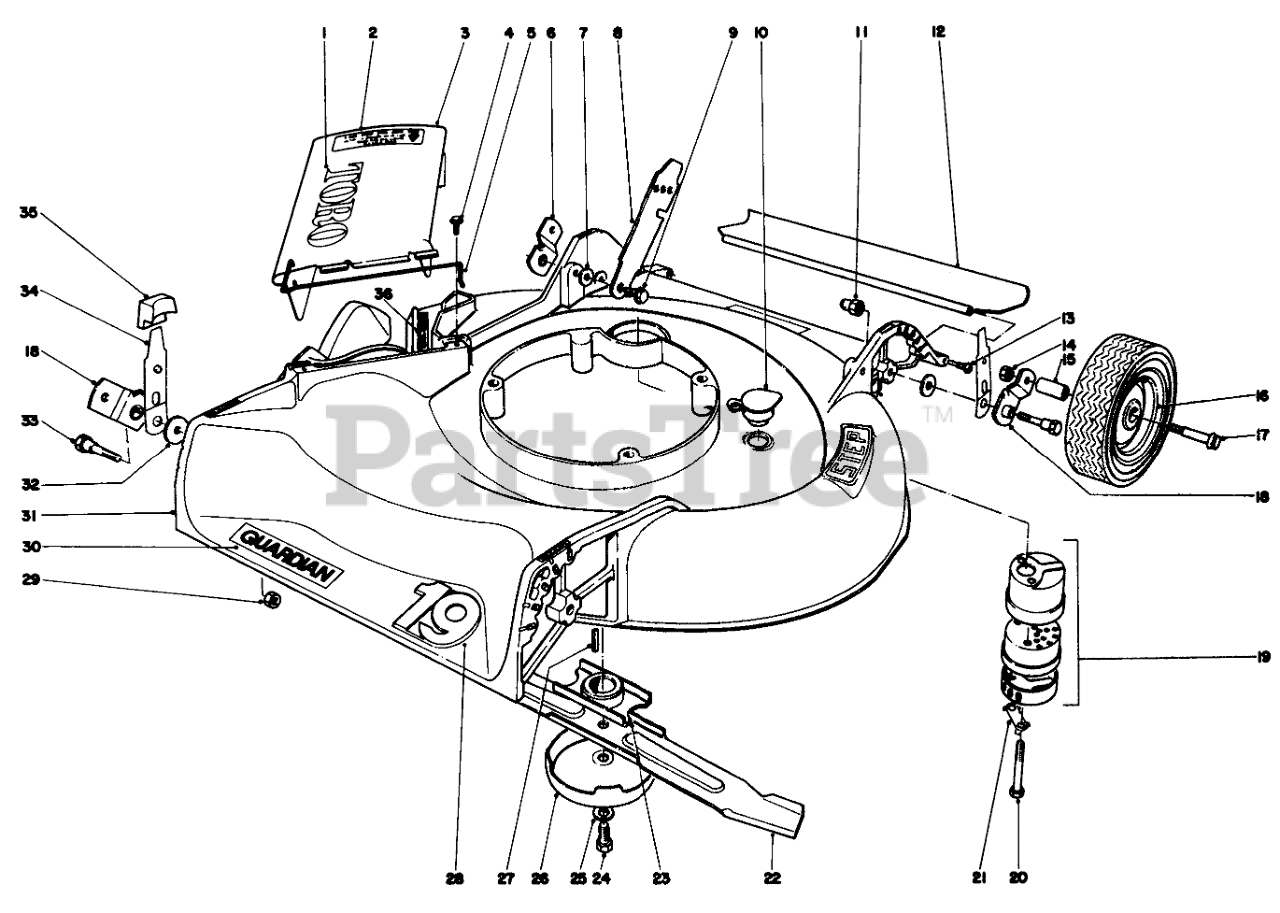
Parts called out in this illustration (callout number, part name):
1	TORO LOGO DECAL
2	Caution Decal
3	Deflector Cover Assembly (Incl. Ref. #1, 2 & 5)
4	SCREW
5	SPRING HINGE
6	Pivot Arm
7	SPACER
8	Latch
9	SCREW-SHOULDER
10	WASHOUT PLUG
11	HANDLE PIVOT NUT
12	SHIELD - TRAILING
13	SAFTEY SHIELD SCREW
14	Nut
15	Bushing
16	Wheel & Tire (Incl. Ref. #15)
18	Pivot Arm
19	Muffler Assy. (Incl. Ref. #20 & 21)
20	SCREW-HH
21	CLIP - LOCKING
22	Blade
23	Blade Retailer
24	SPECIAL SCREW
25	WASHER-LOCK
26	AntiScalp Cup
27	KEY-SQUARE
28	Emblem Deck
29	Nut
30	Decal
31	Housing
32	WASHER-PIVOT
33	5/16-18 PIVOT SCREW
34	SPRING ARM ASM
35	KNOB-ARM
36	Decal
